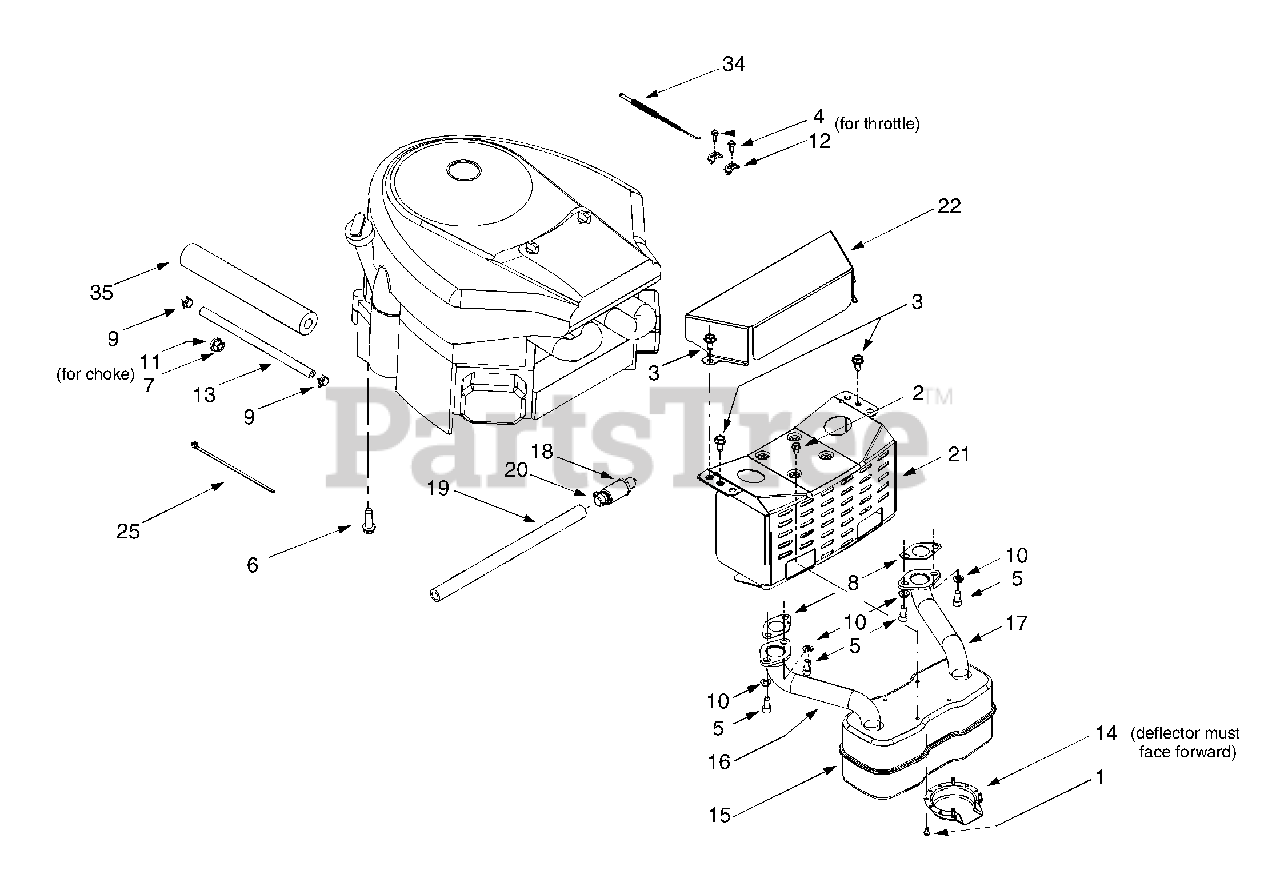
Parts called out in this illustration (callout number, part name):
1	Self-tapping Screw, #8-32 x .375
2	Self-tapping Screw, 1/4-20 x .5
3	Self-tapping Screw, 5/16-18 x .625
4	Screw, #10-32 x .625
5	Socket Cap Screw, 5/16-18 x .625
6	Self-tapping Screw, 3/8-16 x 1.25
7	Hex Nut, 3/8-16
8	Exhaust Gasket
9	Hose Clamp
10	Lock Washer, 5/16
11	Lock Washer, .406 x .875 x .059
12	Casing Clamp
13	Fuel Line Hose
14	Muffler Deflector
15	Muffler, Twin Inlet
16	RH Exhaust Pipe
17	LH Exhaust Pipe
18	Oil Drain Valve
19	Oil Drain Hose
20	Oil Drain Cap
22	Engine Heat Shield
25	Cable Tie
34	Throttle Cable
35	Foam, .625 x 1.5 x 10
